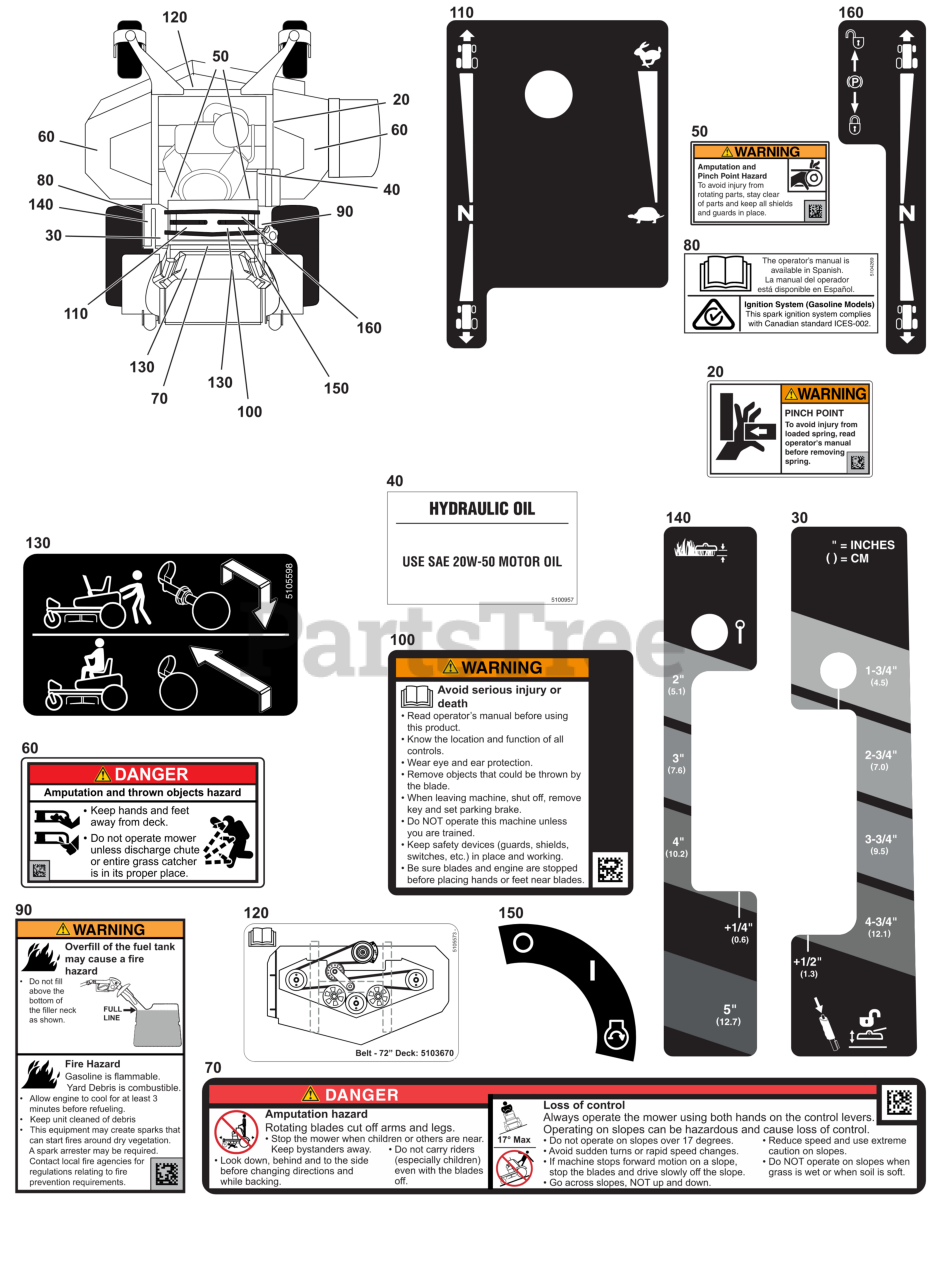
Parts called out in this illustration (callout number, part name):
20	DECAL, Warning/Safety, Pinch Point
30	DECAL, Cutting Height
40	DECAL, Oil
50	DECAL, Warning/Safety, Hand in Belt
60	DECAL, Danger, Cut Hand/Foot
70	DECAL, Danger
80	DECAL
90	DECAL, Warning/Safety
100	DECAL, Warning/Safety
110	DECAL, Controls
120	DECAL, Instruction
130	DECAL, INSTRUCTION
140	DECAL, Cutting Height
150	DECAL, Ignition Switch
160	DECAL, Controls
